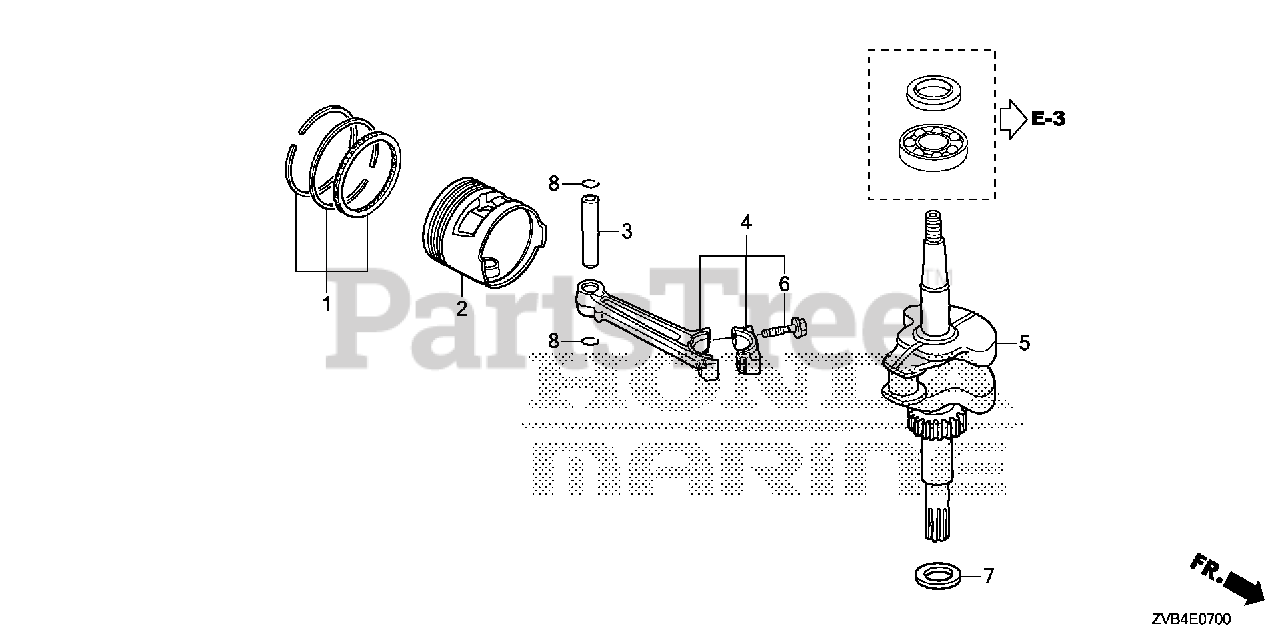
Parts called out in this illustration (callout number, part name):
1	RING SET, PISTON (STD) (TEIKOKU)
3	PIN, PISTON
4	ROD ASSY., CONNECTING
5	CRANKSHAFT
6	BOLT, CONNECTING ROD (IDENT MARK Z)
7	WASHER, THRUST (25MM)
8	CLIP, PISTON PIN (18MM)
